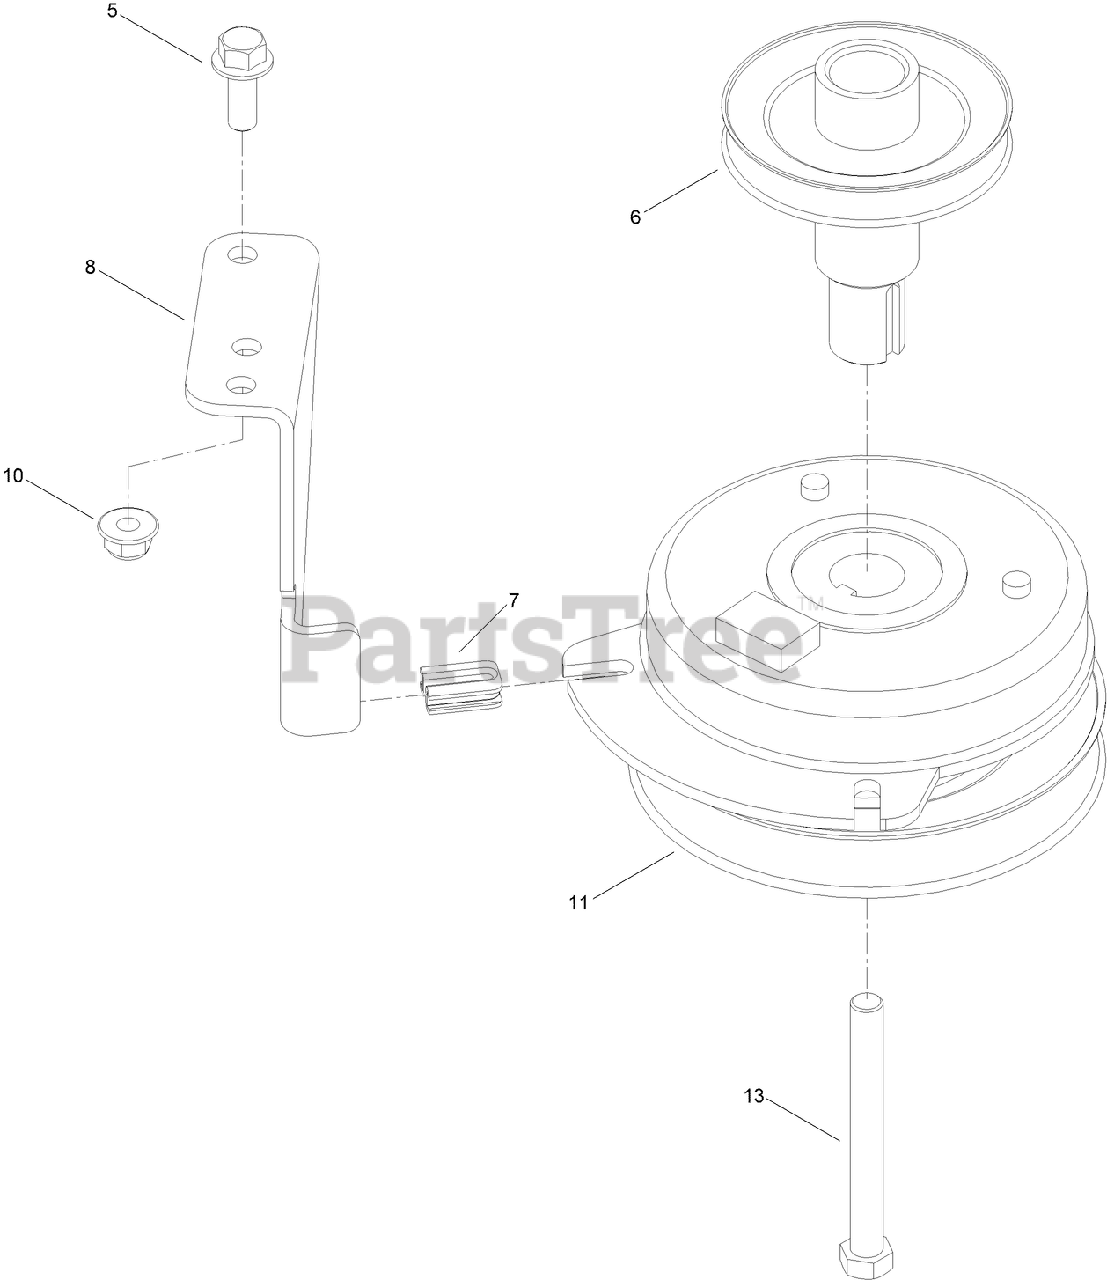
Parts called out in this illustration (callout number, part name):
5	SCREW-HHF
6	PULLEY-ENGINE
7	ISOLATOR-CLUTCH
8	STOP-CLUTCH
10	NUT-HF, NI
11	CLUTCH-PTO
13	SCREW-HH
